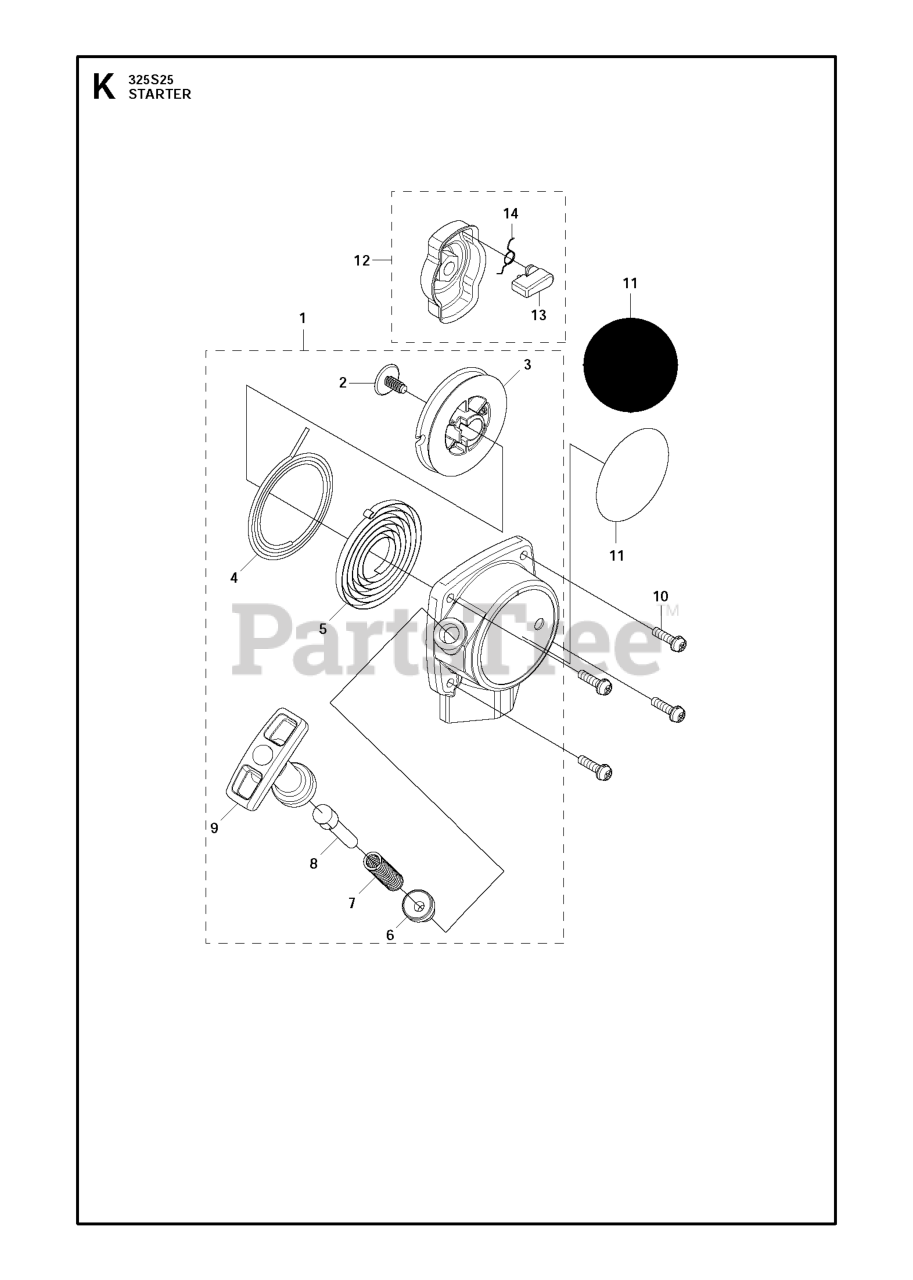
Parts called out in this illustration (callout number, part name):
2	SCREW
5	SPRING, SPIRAL
8	COLLAR (RPLS T160075320)
11	DECAL
